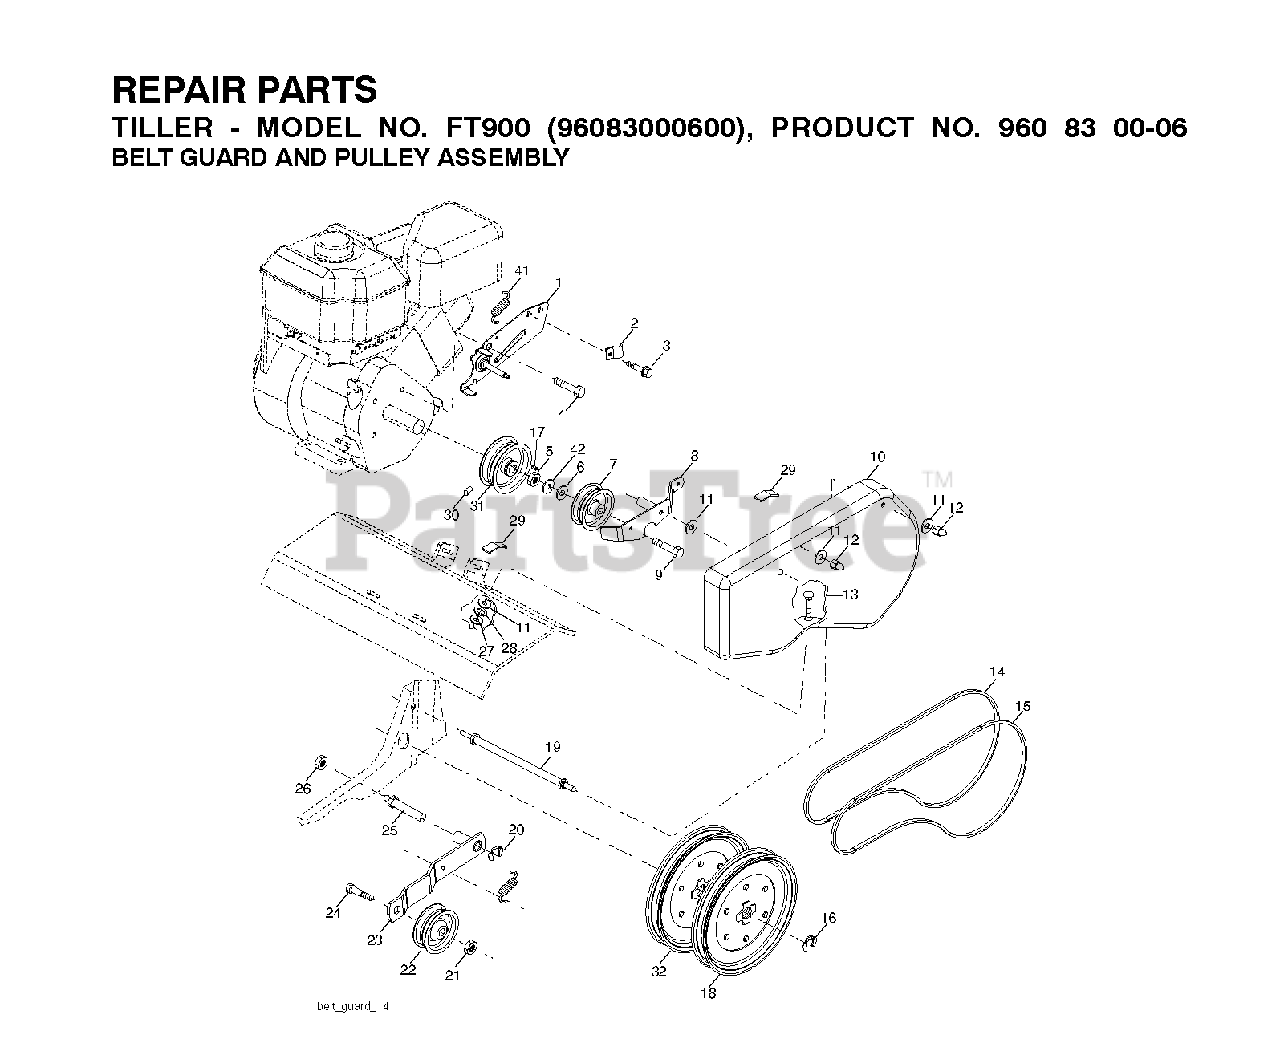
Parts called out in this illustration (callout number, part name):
1	RP ASSEMBLY,BRACKET,BELTGUARD
2	CONDUIT.CLIP.PLATED
3	TAPPING SCREW
4	Bolt, Hex Head 1/2-20 x 3/4
6	WASHER
7	RP PULLEY.IDLER.2.44.TILLER
8	ARM.ASM.REV.IDLER
9	BOLT
10	GUARD.BELT.TILLER.ORANGE
12	CAP
13	BOLT
14	BELT
15	BELT.TILLER.DRIVE
16	RETAINING RING LT
18	SHEAVE,TRANS."D"
19	BOLT.BELT.GUARD
20	KLIP RING TI
21	NUT
22	PULLEY, IDLER
23	ARM.ASM.IDLER.BLACK
25	SHAFT.IDLER.TILLER
26	JAM NUT TI
27	NUT
28	LOCKWASHER
29	PAD IDLER TI
31	ENGINE.PULLEY.TILLER
32	SHEAVE.TRANS
41	SPRING.EXTENSION
